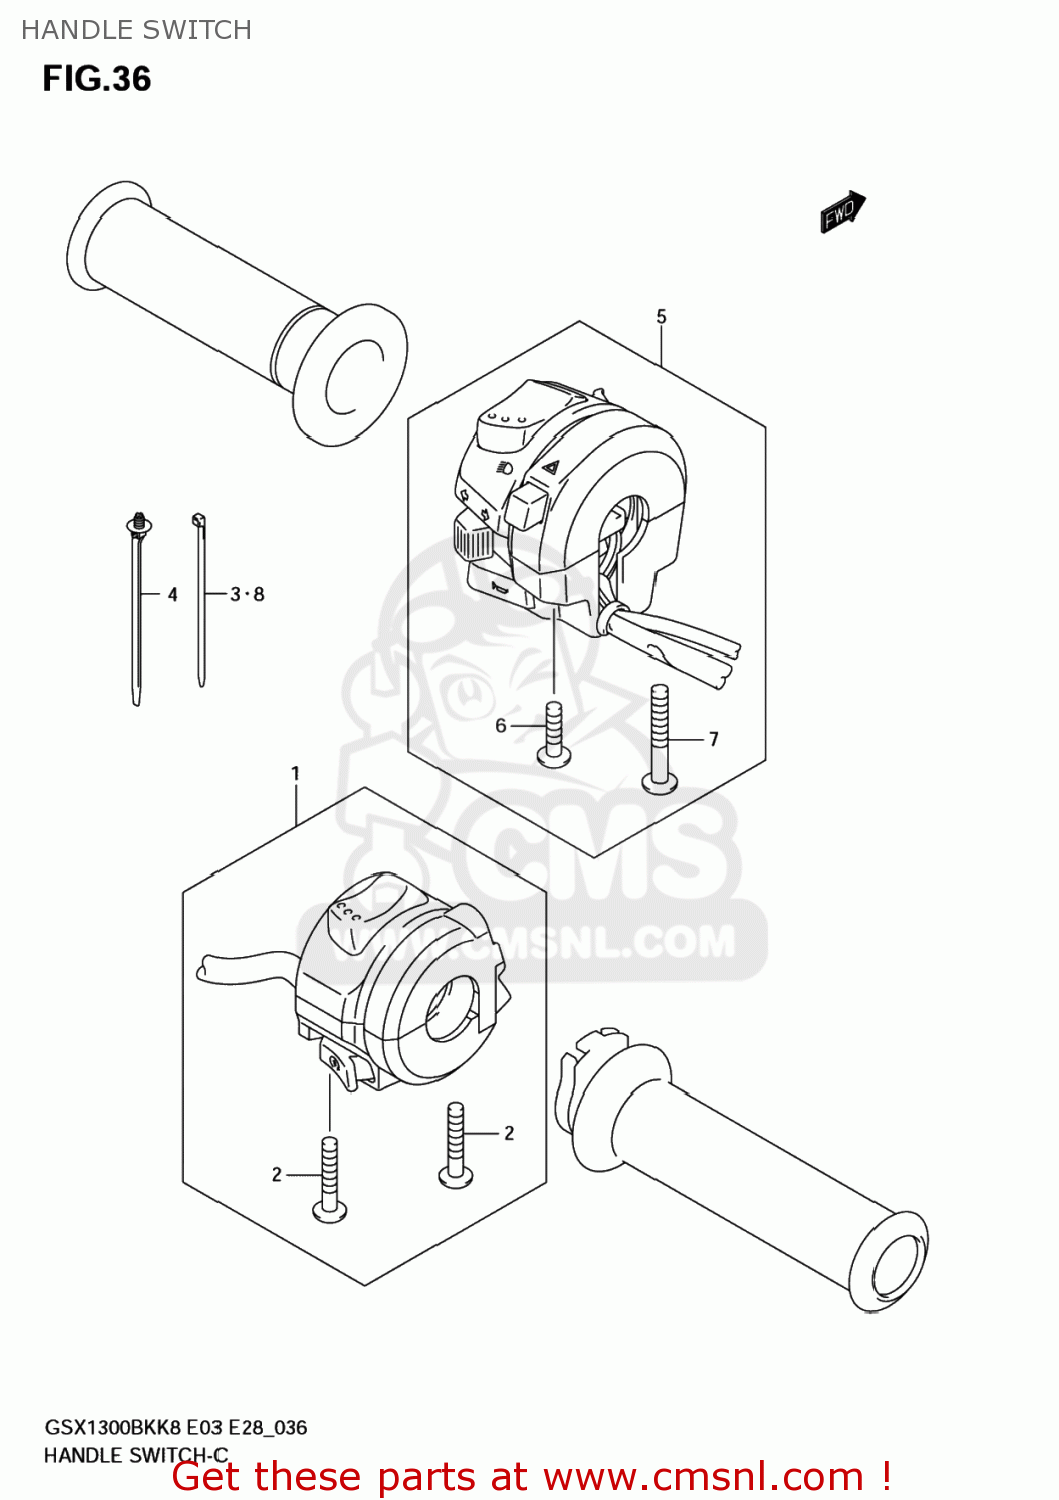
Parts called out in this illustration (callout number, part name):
1	SWITCH ASSY,HA
2	SCREW
3	CLAMP(L:145)
4	CLAMP(L:154)
5	STUURSCHAKELAAR
6	SCREW
7	SCREW
8	CLAMP(L:145)
